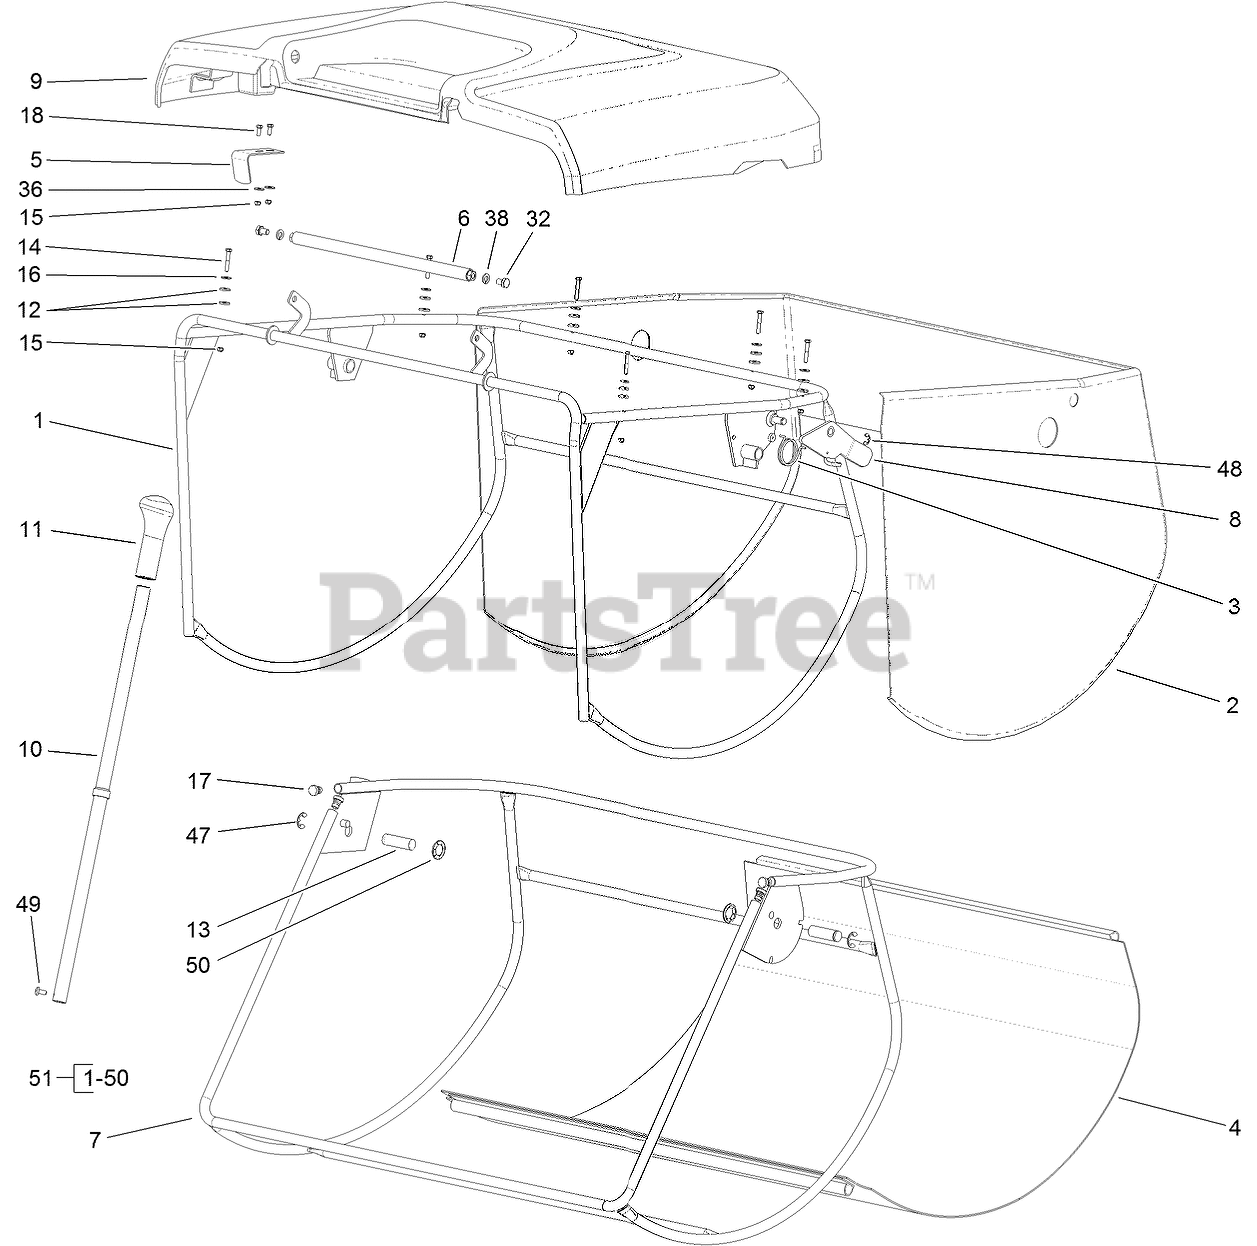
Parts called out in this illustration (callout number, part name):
1	FRAME ASM
2	BAG-GRASS, UPPER
3	SPRING
4	BAG-GRASS, LOWER
5	SPRING-COIL, INTERLOCK SWITCH
6	HANDLE-LIFT
7	LOWER FRAME ASM
8	LEVER-ARRESTMENT
9	COVER-COLLECTOR
10	LEVER-DUMP
11	HANDLE-MULCHING
12	WASHER-FLAT
15	NUT-LOCK
16	WASHER-RUBBER
32	SCREW-HHF
36	WASHER
38	WASHER-SPRING
47	E-CLIP
48	RING-LOCKING
50	RING-LOCK
51	GRASS COLLECTOR ASM
